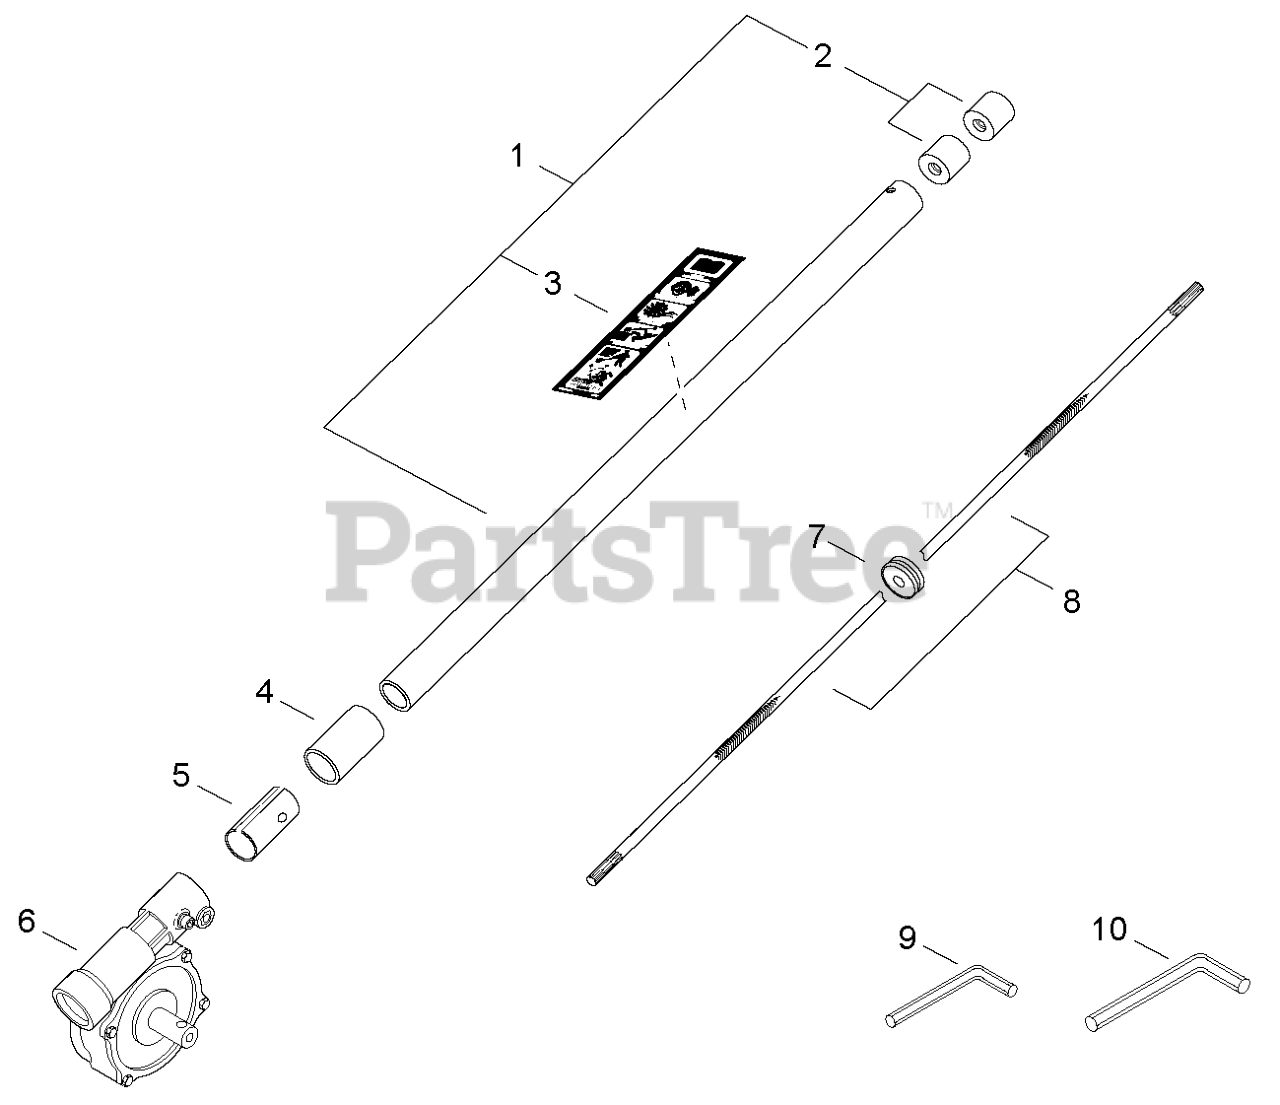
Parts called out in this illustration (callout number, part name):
1	MAIN PIPE ASSY
2	BUSHING
3	LABEL - CAUTION
6	GEAR CASE ASSY
7	BUSHING
8	DRIVESHAFT
9	HEX KEY - 4mm
10	HEX KEY - 6mm
